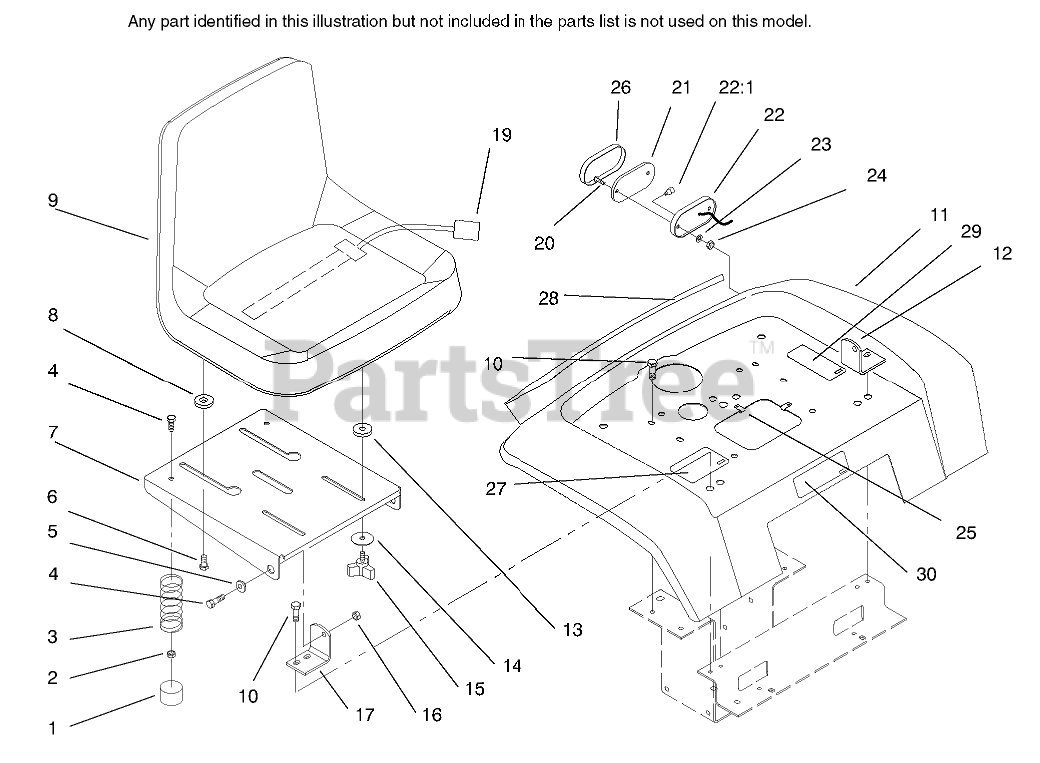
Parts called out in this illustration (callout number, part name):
1	CAP-PROTECTOR
2	NUT-LOCK, NI
3	SPRING-COMPRESSION
4	SCREW-HH
5	BUSHING
6	BOLT-SHOULDER
7	SUPPORT - SEAT (BLACK)
8	SPACER-NYLON
9	SEAT-V-511
10	Bolt
12	BRACKET-PIVOT, LH
13	SPACER-NYLON
14	WASHER
16	NUT-LOCK, NI
17	BRACKET-PIVOT, RH
19	SWITCH-SEAT
20	SCREW-PPH
22	BASE-TAIL LIGHT
23	WASHER-LOCK, INT
24	NUT-LOCK, NI
25	SPEED CLIP
26	LENS-TAIL LIGHT
28	DECAL - REAR FENDER
